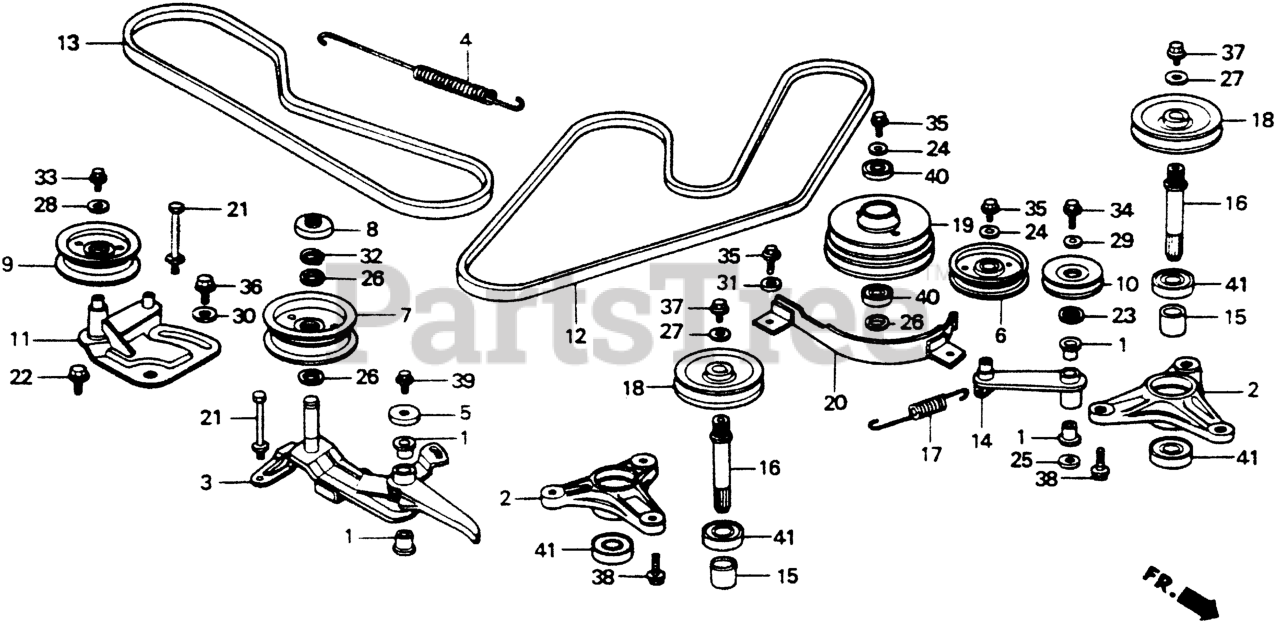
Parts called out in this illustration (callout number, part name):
1	BUSH (15X19X22)
2	HOUSING, BEARING (NOT AVAILABLE)
3	ARM, TENSION (DECK)
4	SPRING, TENSIONER ARM
5	CAP, TENSION ARM
6	ROLLER, TENSIONER
7	ROLLER, TENSIONER
8	DUST COVER, TENSION PULLEY (NOT AVAILABLE)
9	PULLEY, TENSIONER
10	PULLEY, IDLER
11	ARM, BELT ADJUSTING
12	V-BELT, BLADE (SB-65)
13	V-BELT, DECK (SB-61)
14	ARM, TENSION (BLADE) (NOT AVAILABLE)
15	COLLAR, BLADE SHAFT
16	SHAFT, BLADE (112.5MM)
17	SPRING, TENSIONER ARM (BLADE)
18	PULLEY, BLADE (NOT AVAILABLE)
19	PULLEY, DRIVEN (NOT AVAILABLE)
20	STOPPER, BELT
21	BOLT, BELT STOPPER
22	BOLT, ADJUSTING ARM
23	WASHER (12.5MM)
24	WASHER (8MM)
25	WASHER (12MM) (NOT AVAILABLE)
26	WASHER (17.3X25)
27	WASHER (10.3MM)
28	WASHER, PLAIN (6MM)
29	WASHER, PLAIN (6MM)
30	WASHER, PLAIN (8MM)
31	WASHER, PLAIN (8MM)
32	CIRCLIP (OUTER) (17MM)
33	BOLT, FLANGE (6X12) Use up to Engine SN 1543277.
34	BOLT, FLANGE (6X12) Use from Engine SN 2086984.
35	BOLT, FLANGE (8X14)
36	BOLT, FLANGE (8X16) Use from Engine SN 1000016.
37	BOLT, FLANGE (10X16)
38	BOLT, FLANGE (10X28)
39	BOLT, FLANGE (6X12) Use from Frame SN 1001725.
40	BEARING, RADIAL BALL (6203UU)
41	BEARING, RADIAL BALL (6204UU)
